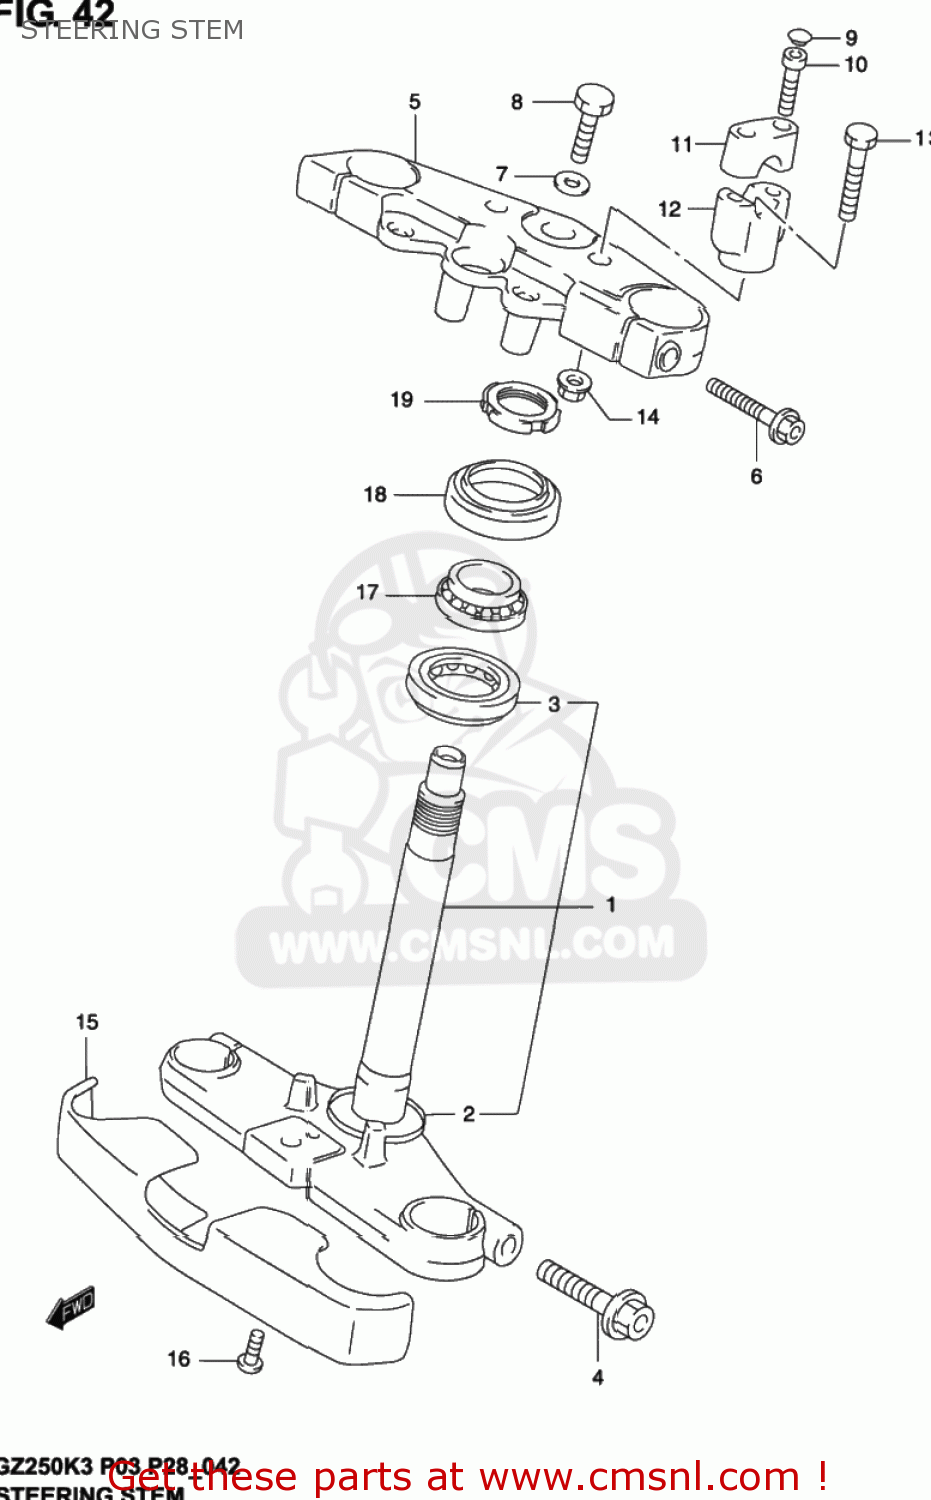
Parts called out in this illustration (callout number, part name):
1	STEM, STEERING
2	SEAL,STEERING LWR
3	BEARING(30X55X17)
4	BOLT
5	HEAD,STEERING STEM
6	BOLT
7	WASHER
8	BOLT,STEERING STEM HEAD
9	CAP(OD:11)
10	BOLT
11	HOLDER,HANDLE UPR
12	HOLDER, HANDLE LOWER
13	BOLT
14	NUT
15	COVER,FR FORK UNDER
16	SCREW(6X16)
17	BEARING(25X47X15)
18	DUST SEAL,STEERING UPR
19	NUT,STEERING STEM(25X44X10)
